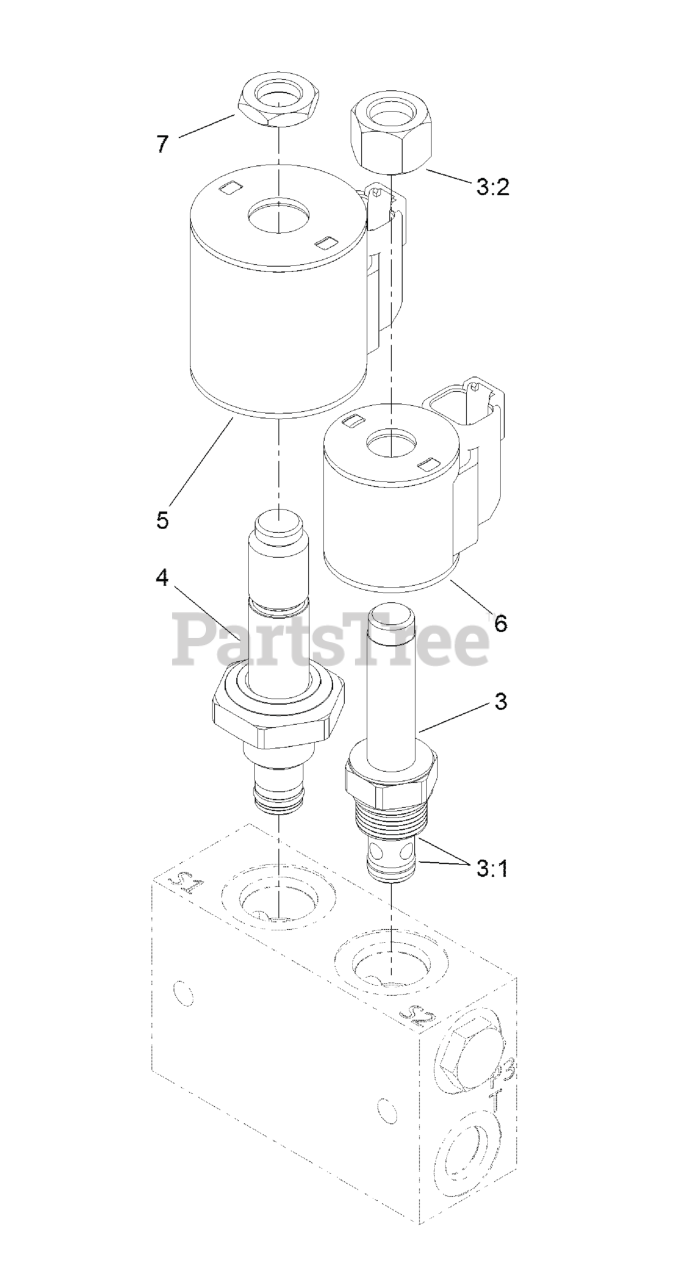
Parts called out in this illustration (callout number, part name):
3	VALVE-SOLENOID
3:1	SEAL KIT
3:2	NUT-SOLENOID
4	VALVE-SOLENOID
5	COIL-12V
7	NUT-COIL
